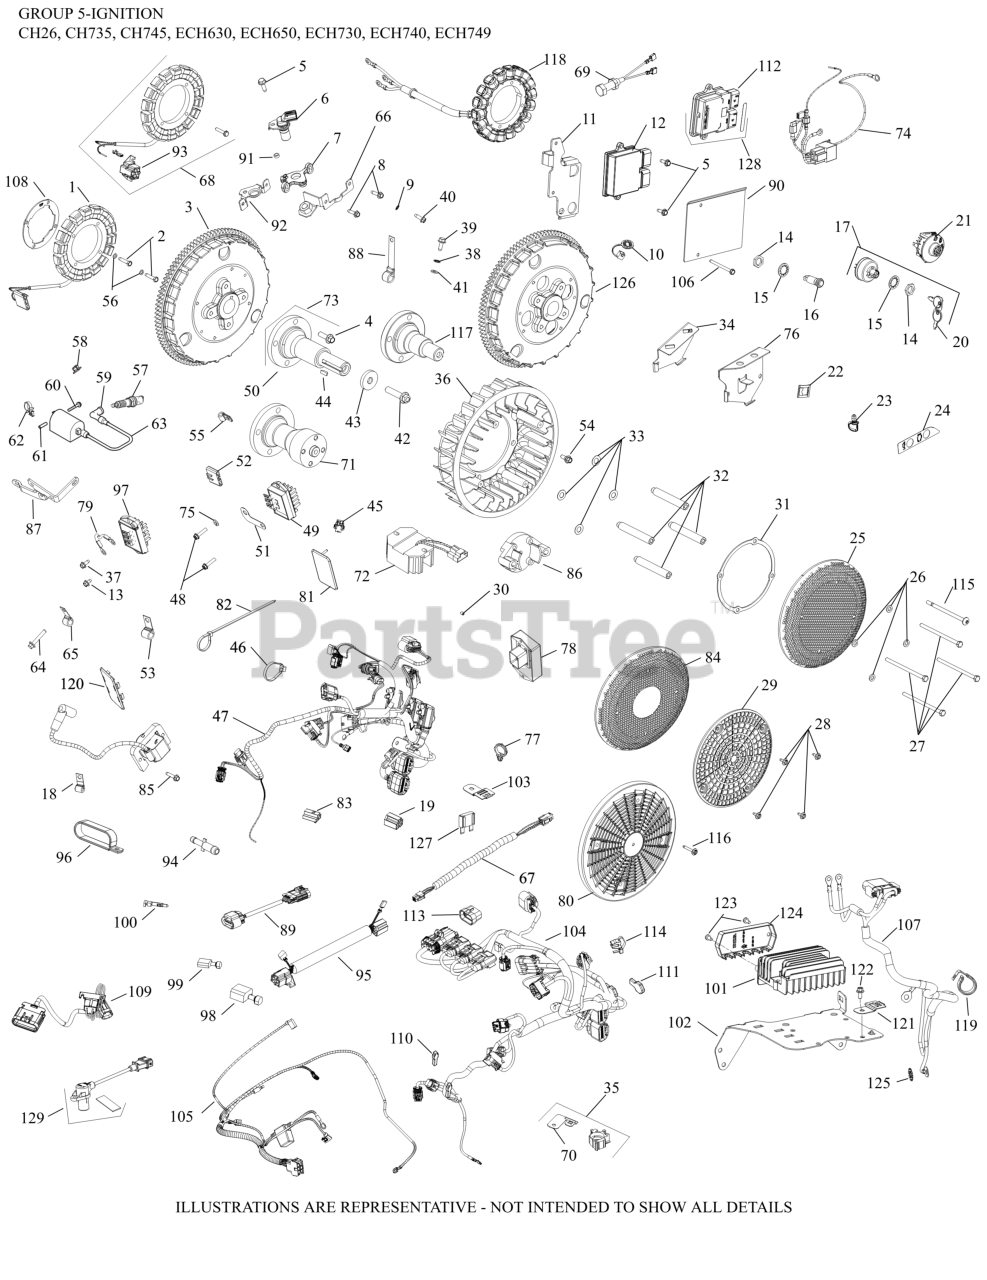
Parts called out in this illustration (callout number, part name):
2	SCREW, THREAD FORMING
3	FLYWHEEL, ASSEMBLY
6	SENSOR, SPEED
8	SCREW, THREAD FORMING
9	WASHER, INT TOOTH LOCK #10
10	CAP, CONNECTOR
11	BRACKET, ECU
12	MODULE, ECU
25	KIT GRASS SCREEN
28	SCREW, FLG SEMS M4x.7x25
30	SCREW, FLG M10X1.5X45-USE 25 086 361-S
35	KIT, MOUNTING CLIP
36	FAN-USE 24 755 253-S
37	SCREW, THREAD FORMING
38	WASHER, INT TOOTH LOCK 1/4"
41	WASHER, FLAT 1/4" (O.D. 1/2")
43	WASHER, FLAT 13/32"
44	KEY, 3/16" X 5/8"
47	HARNESS, WIRING ASSEMBLY
48	SCREW, HEX FLANGE HI-LO
52	CONNECTOR
54	BOLT, SHOULDER
57	PLUG, SPARK (STD)
62	CLIP, SNAP-IN-USE 25 018 05-S
63	COIL, IGNITION - EFI
64	SCREW, FLG (BLACK) M6X1.0X34
68	KIT, 25 AMP STATOR ASSY.
70	CLIP USE 25 154 21-S
77	RETAINER, WIRE HARNESS
80	SCREEN, GRASS
92	BRACKET, SENSOR
93	CONNECTOR
97	REGULATOR, RECT (20-30AMP, FW W/OVP)
